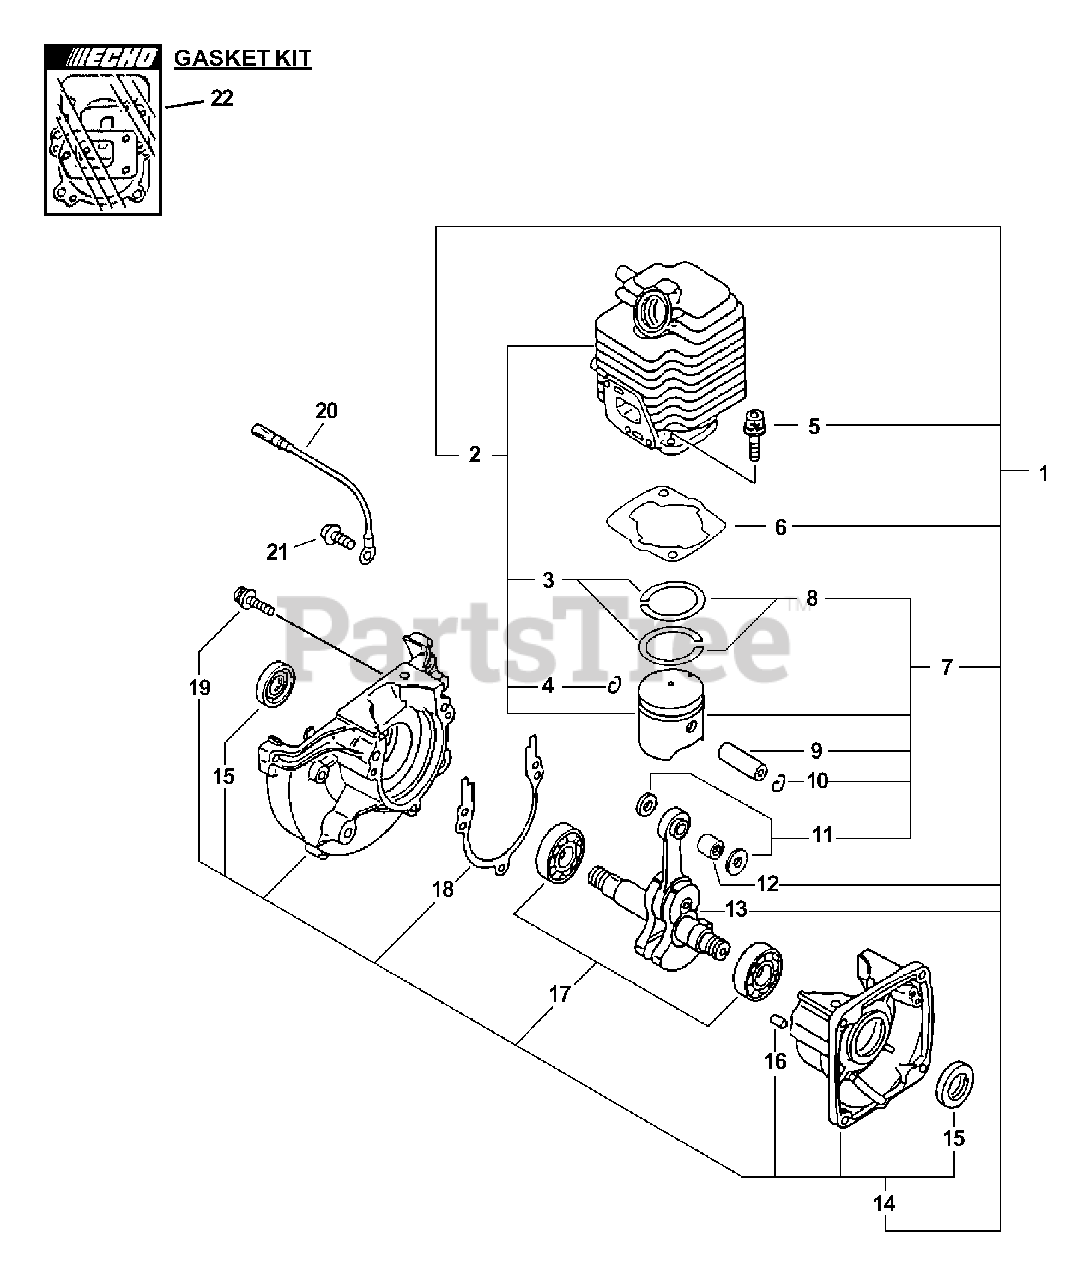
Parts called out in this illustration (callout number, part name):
1	SHORT BLOCK ES-2400
2	CYLINDER/PISTON KIT
3	RING, PISTON
4	RING, SNAP
5	BOLT 5×22
6	GASKET, CYLINDER
7	PISTON KIT
8	RING, PISTON
9	PIN, PISTON 8
10	RING, SNAP
11	WASHER, THRUST
12	BEARING, NEEDLE
13	CRANKSHAFT ASSY
14	CRANKCASE KIT
15	SEAL, OIL 12
16	PIN, LOCATING 4
17	BEARING, BALL - 6201 C3
18	GASKET, CRANKCASE
19	BOLT 5×28
20	LEAD - GROUND
21	SCREW 4×22
22	GASKET KIT
